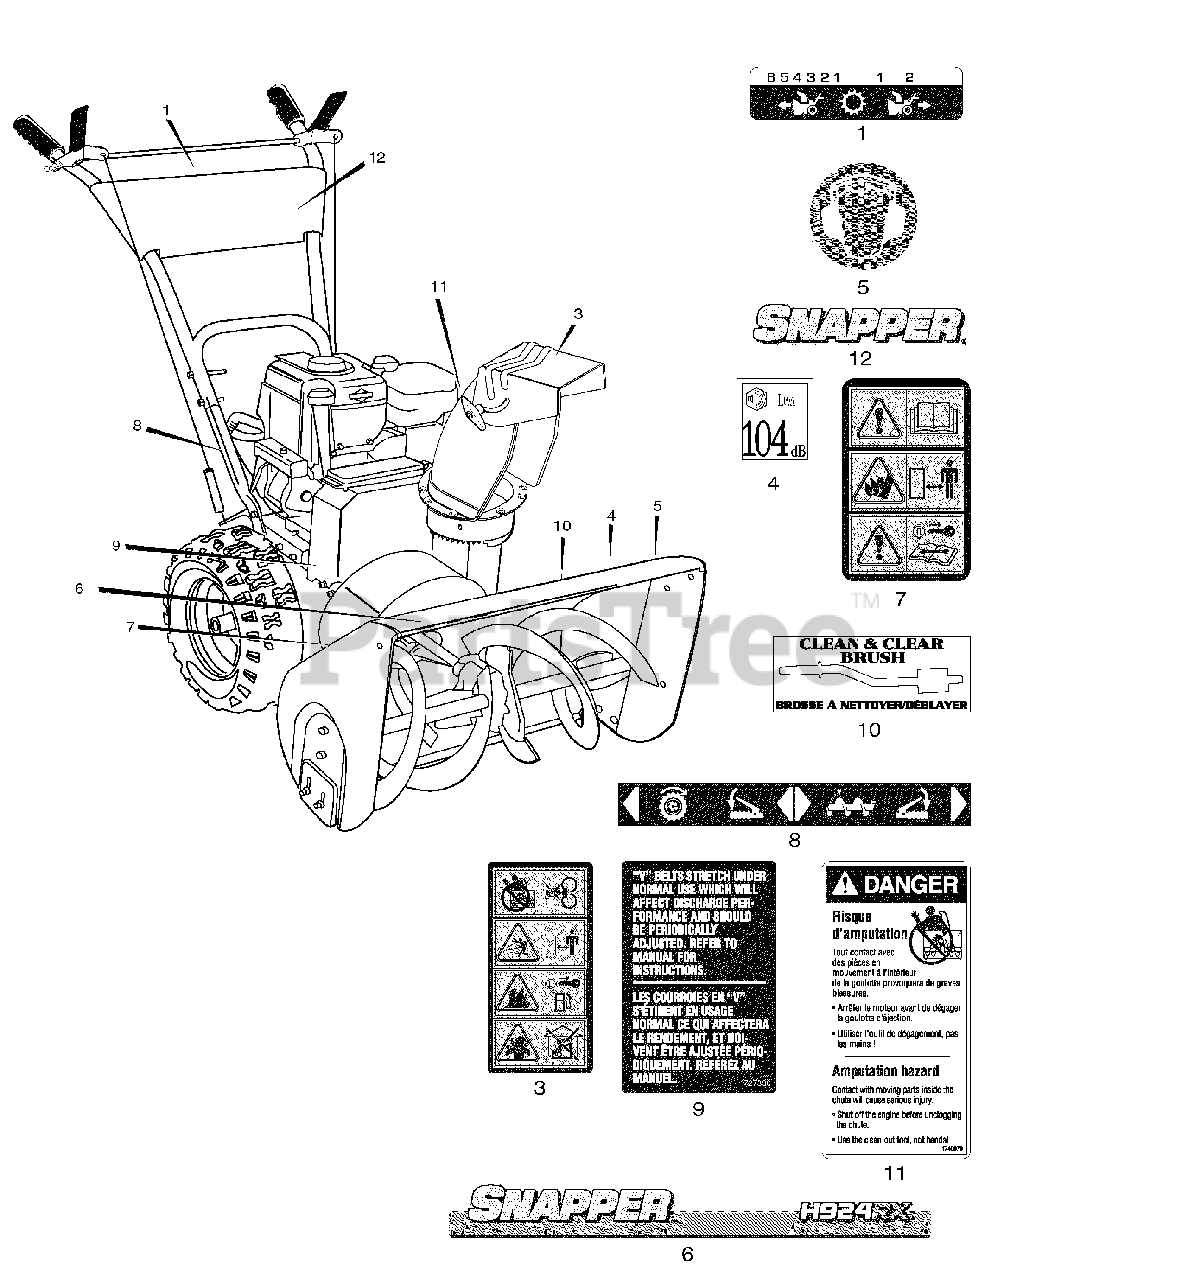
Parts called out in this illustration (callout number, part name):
1	DECAL, Gear Select
3	DECAL, ISO Chute CE
4	DECAL, 104db CE
5	DECAL, Face, Head Phones
6	DECAL, Model Number
7	DECAL, ISO Auger CE
8	DECAL, Traction, Auger
9	DECAL, Belt Adjustment
10	DECAL, Clean & Clear Brush
11	DECAL, Danger, Chute
12	DECAL, Snapper Logo
